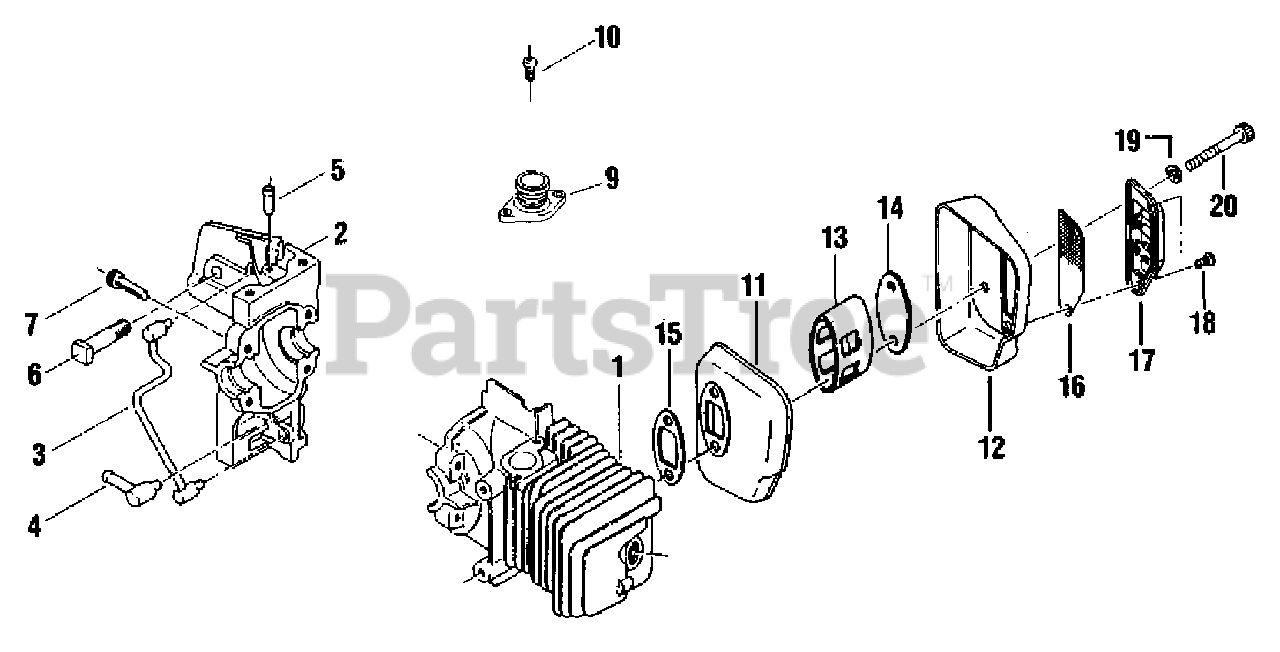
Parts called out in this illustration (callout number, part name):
1	CYLINDER
2	CRANKCASE
3	TUBE, CRANKCASE OIL
4	ELBOW
5	PULSE JOINT
6	BOLT, BAR
7	SCREW - 5X18
9	BOOT
10	SCREW - 4X14
11	BASE, MUFFLER
12	COVER, MUFFLER
13	BAFFLE, MUFFLER
14	PLATE, MUFFLER
15	GASKET
16	SCREEN, SPARK ARRESTOR
17	COVER, SCREEN
18	SCREW - 4X8
19	WASHER
20	SCREW - 5X45
